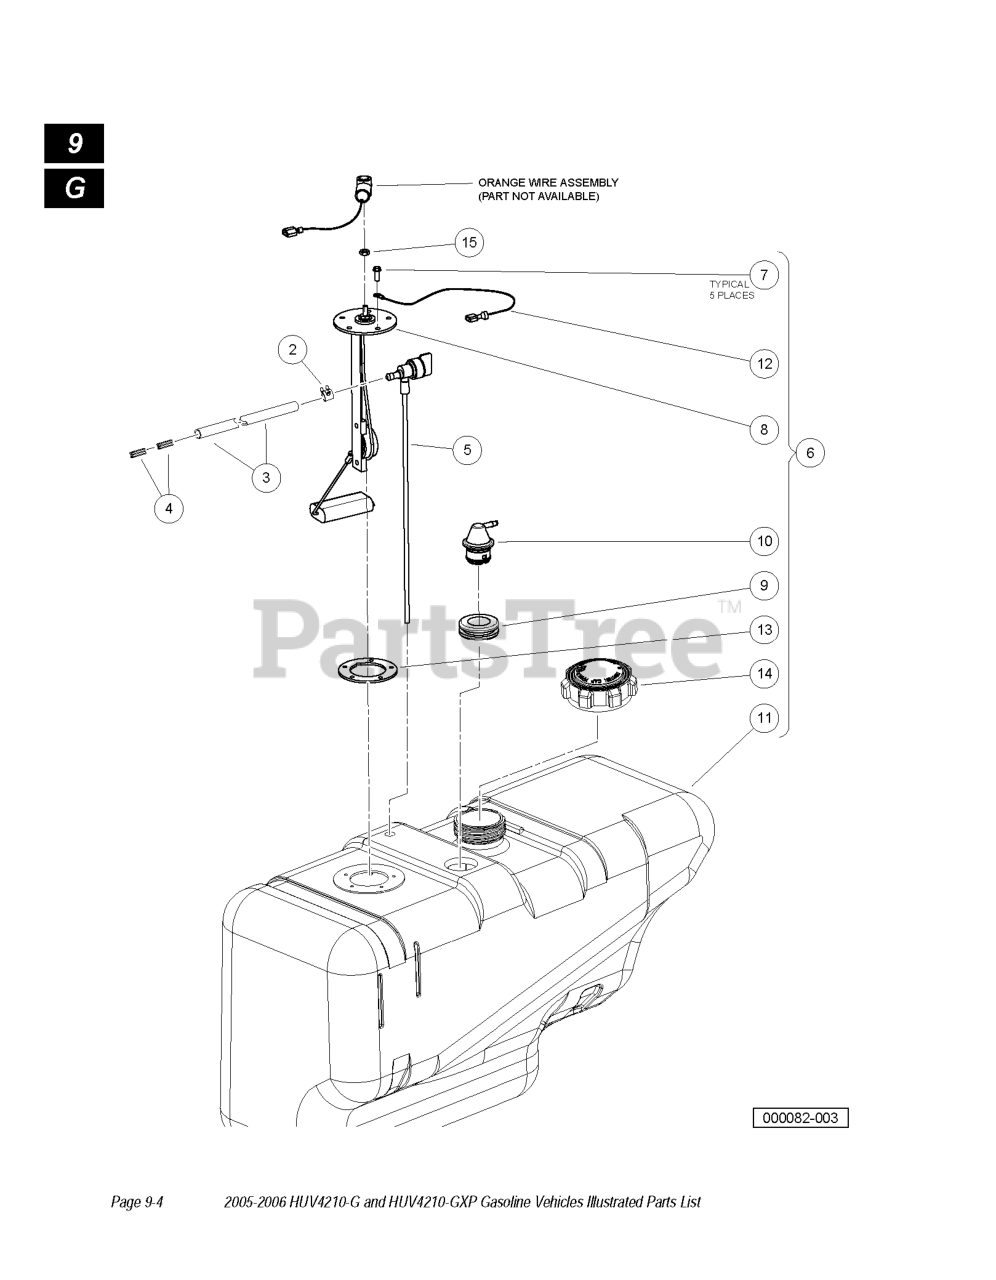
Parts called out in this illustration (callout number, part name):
1	TANK KIT W/ SENDING UNIT
3	FUEL LINE
5	FUEL PICKUP W/ SHUTOFF
9	INSULATION GROMMET
10	FUEL TANK VENT ASSY
13	GASKET, SEND UNIT (RUBBER)
14	CAP, FUEL TANK - GASOLINE
15	NUT, #10-32 BRASS HEX
